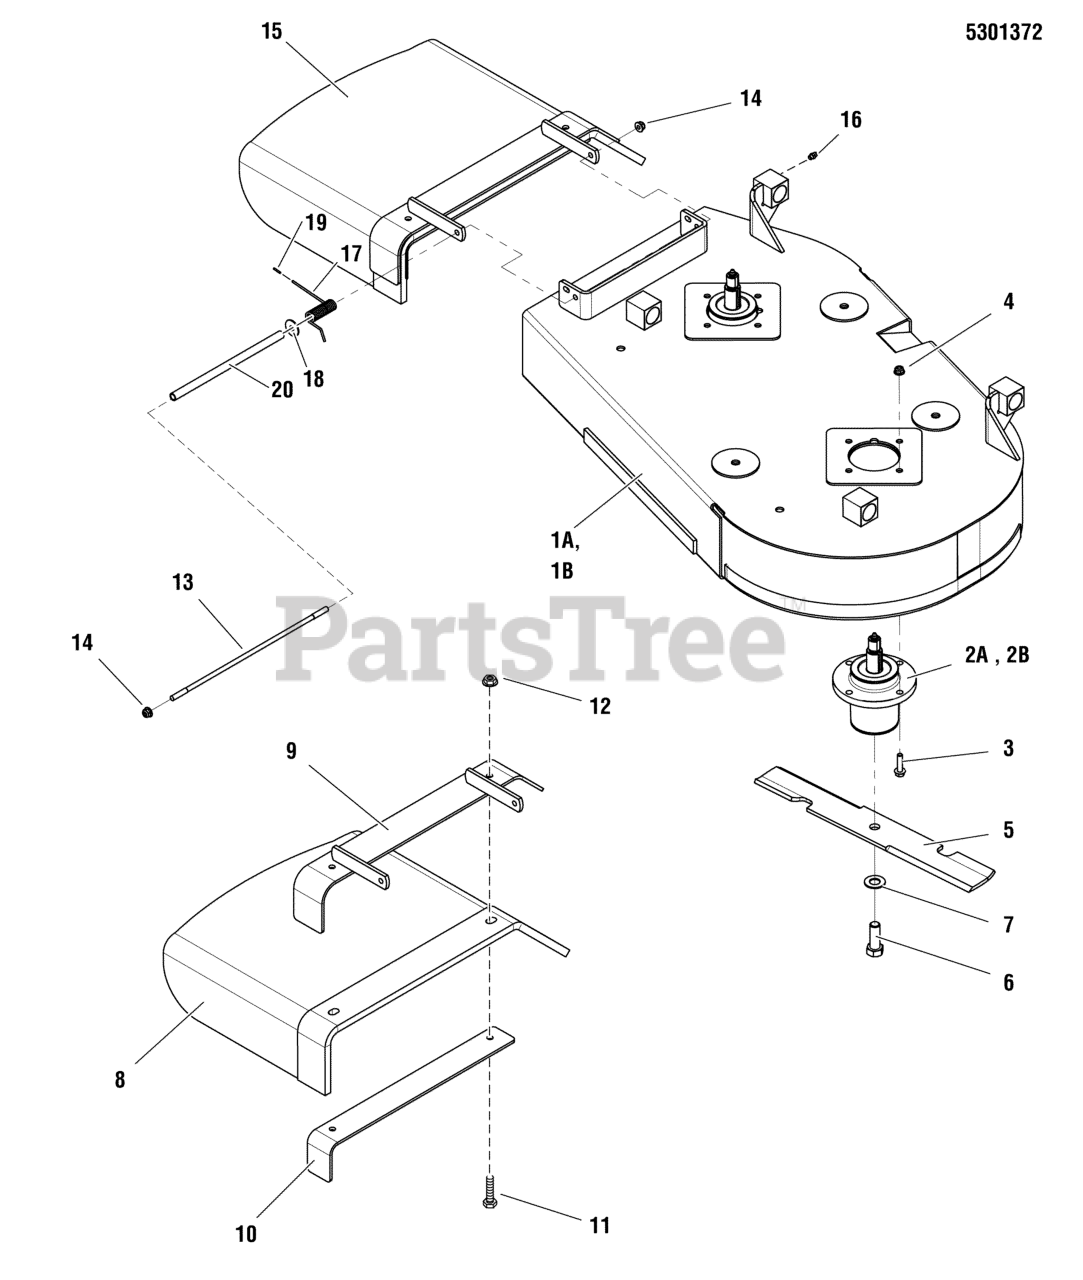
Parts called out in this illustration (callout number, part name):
3	BOLT, 5/16-18 X 1 1/4 FLANGE
4	NUT, 5/16-18 HEX NYLOCK FLANGE
5	BLADE, 18
6	BOLT, 5/8-11 X 1-3/4 GD8
7	WASHER, 5/8" GRADE 8, YZ
8	CHUTE, DISCHARGE, RUBBER, BENT (SV)
9	WELD, MOUNT, DISCHARGE CHUTE - BLK
10	SUPPORT, DISCHARGE CHUTE, 44/48/52 - BLK
11	BOLT, 3/8-16 X 1-1/2" GD5 CZ
12	NUT, 3/8-16 HEX NYLOCK FLANGE
13	ROD, BRAKE LINKAGE
14	NUT, 5/16-24 HEX NYLON LOCK
15	KIT, DISCHARGE CHUTE, 44/48/52
16	GREASE FITTING, 1/4-28 STRAIGHT
17	SPRING, TORSION
18	WASHER, 5/16 FENDER
19	CAP, PROTECTOR, .120 ID
20	SPACER, TORSION SPRING, 9.63 LG
